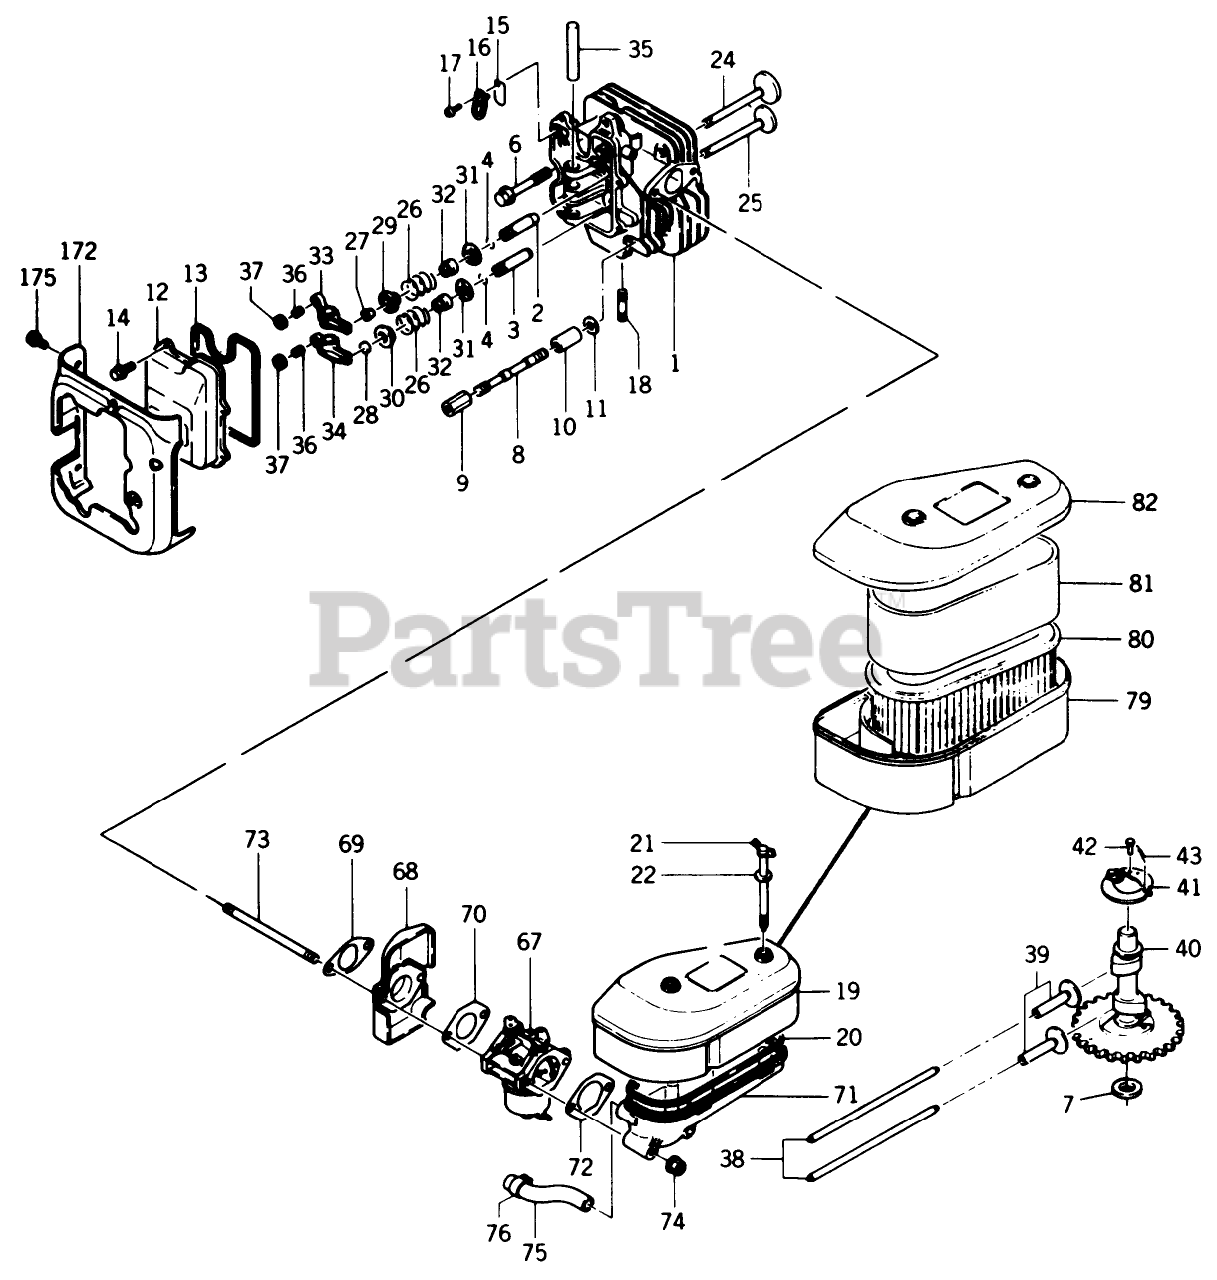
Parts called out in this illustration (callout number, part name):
12	Rocker Case
19	Air Filter Assembly
26	ORDER KAWASAKI#49078-2061
70	GASKET
81	WRAPPER AIR FILTER
